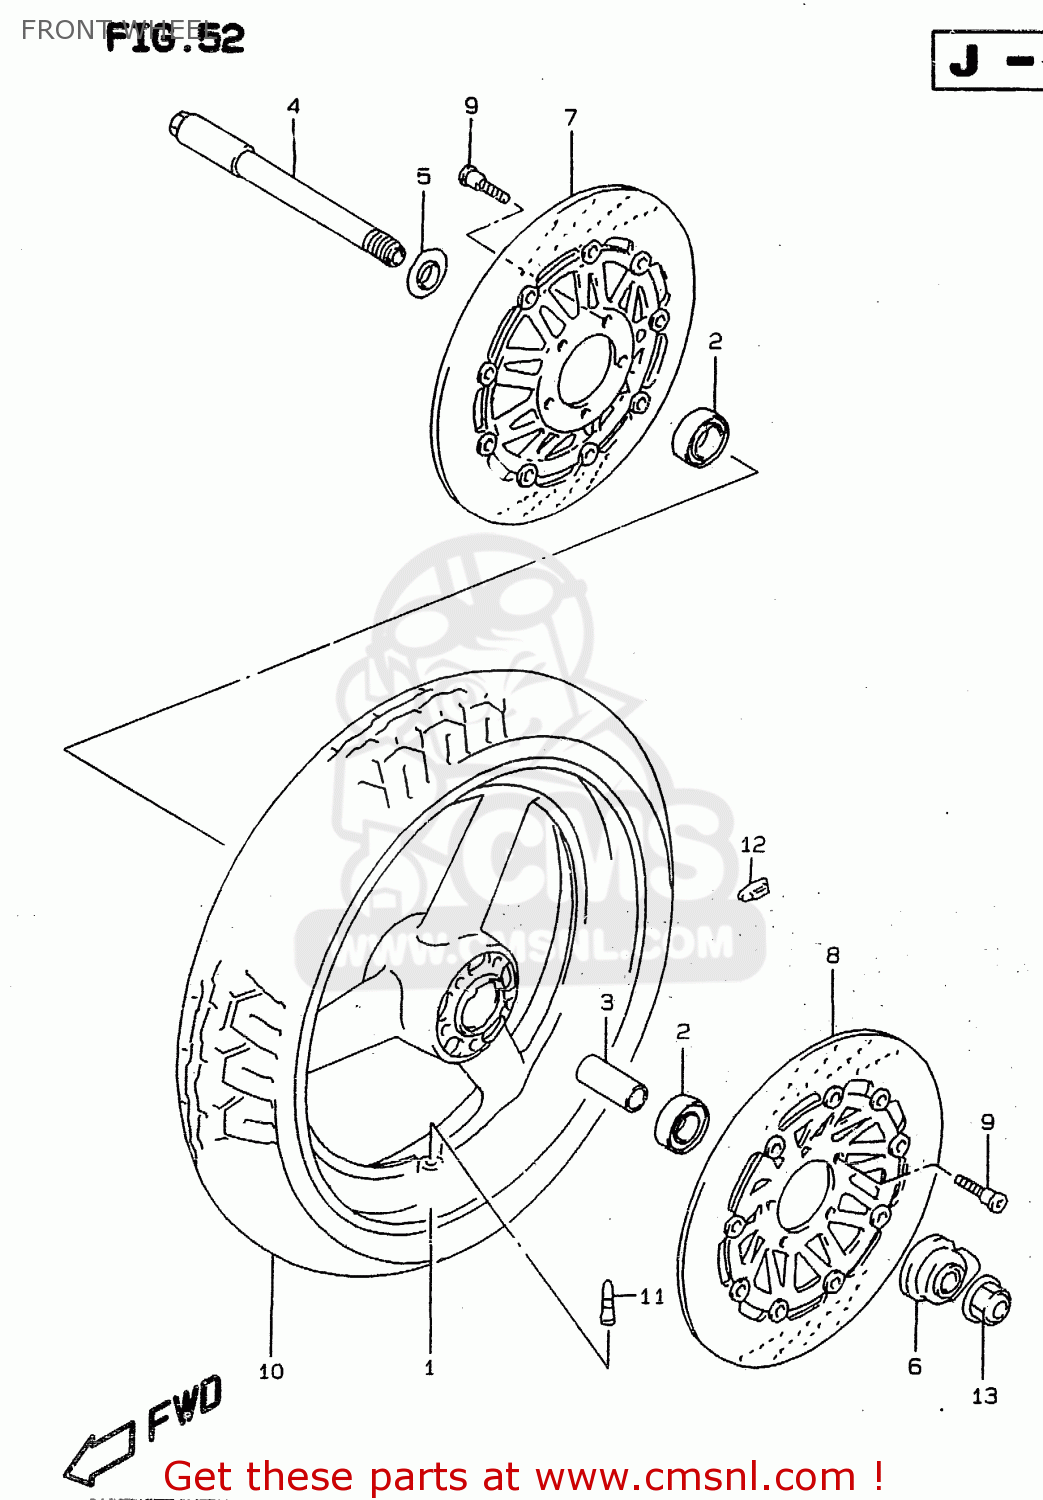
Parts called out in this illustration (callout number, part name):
1	WHEEL,FRONT (MT3.50X17)
2	BEARING
3	SPACER(20.8X27.2X74)
4	AXLE,FR
5	SPACER,FR HUB BEARING,R
6	BOX ASSY,SPEEDOMETER GEAR
7	DISC,FR BRAKE,R
8	DISC,FR BRAKE,L
9	BOLT 8X33
10	TIRE,FRONT 120/70 ZR17
11	VALVE ASSEMBLY,WHEEL,TR412
12	BALANCER,WHEEL (10G)
13	NUT
